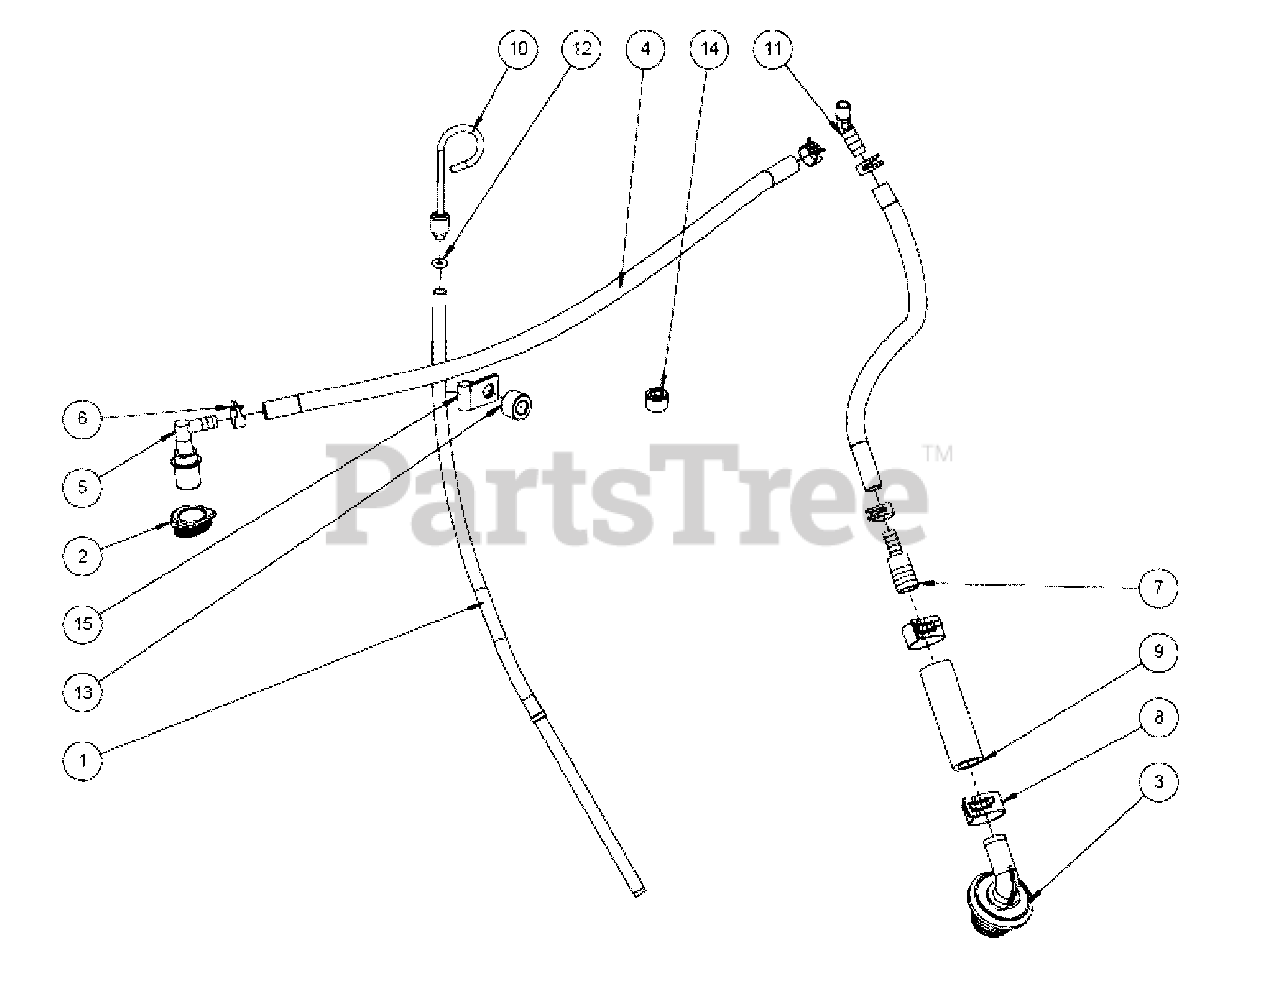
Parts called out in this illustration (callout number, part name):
1	* TUBE
11	* FITTING
12	* O-RING
13	* SPACER
14	* PLUG
15	* CLAMP
